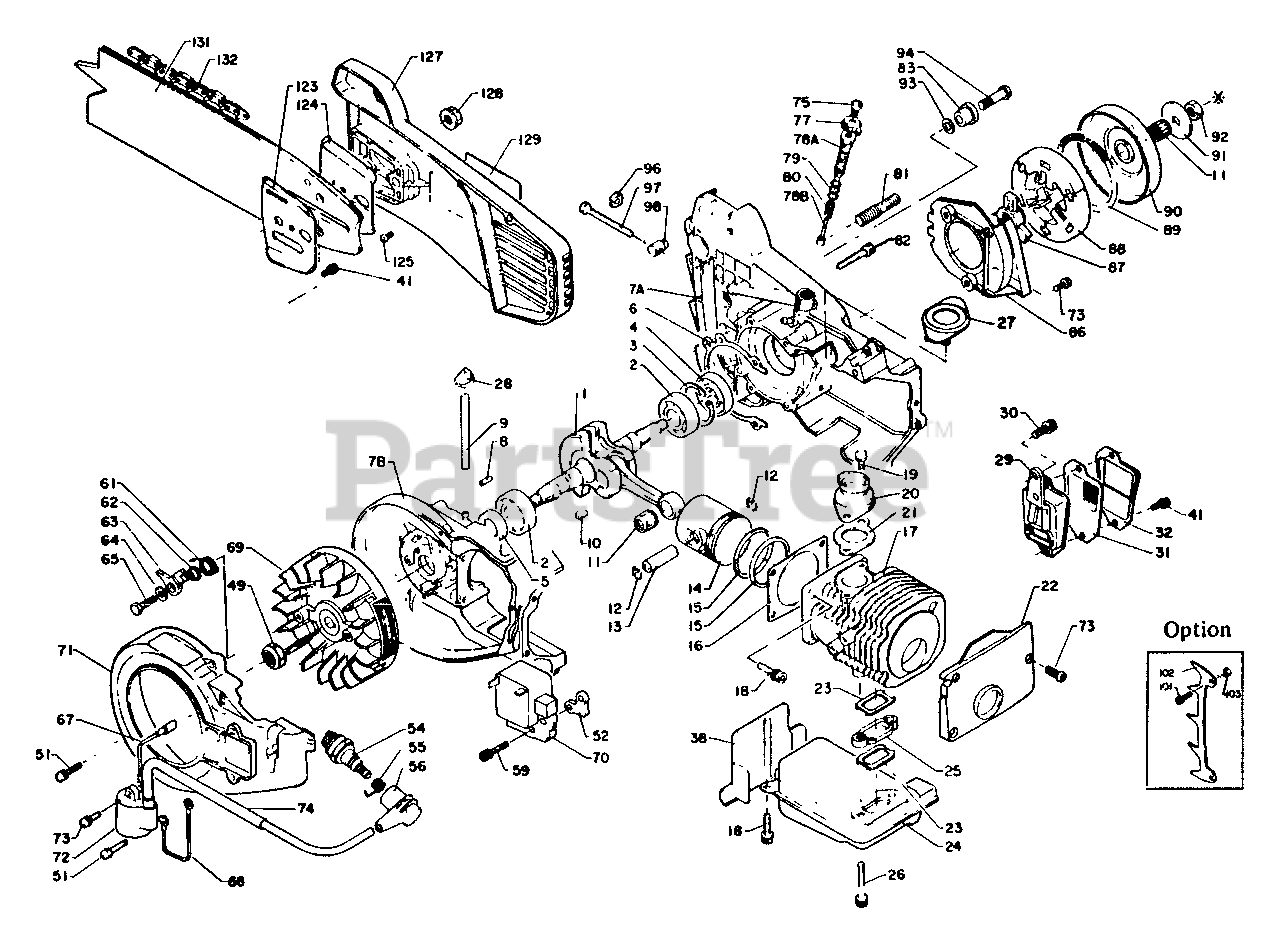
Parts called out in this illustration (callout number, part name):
1	CRANKSHAFT ASSY
2	BEARING, BALL 6202
3	RING, SNAP 35
4	SEAL, OIL 18
5	SEAL, OIL
6	GASKET, CRANKCASE
7	CRANKCASE KIT
7A	CRANKCASE KIT
7B	CRANKCASE KIT
8	PIN, LOCATING 4
9	PIPE, IMPULSE 3×6×75
10	KEY, WOODRUFF
11	BEARING, NEEDLE
12	RING, SNAP 8
13	PIN, PISTON
14	PISTON
15	RING, PISTON
16	GASKET, CYLINDER
17	CYLINDER
18	BOLT 5×20
19	SCREW 5×10
20	ADAPTOR, INTAKE
21	GASKET, INTAKE
22	COVER, CYLINDER
23	GASKET, EXHAUST
24	MUFFLER
25	BAFFLE, MUFFLER
26	BOLT 5×45
30	BOLT 5×14
31	SCREEN, SPARK ARRESTER
32	GUIDE, EXHAUST
38	INSULATOR
41	SCREW 4×10
51	SCREW 4×20
54	SPARK PLUG - BPM6A
55	TERMINAL, SPARK PLUG
56	CAP, SPARK PLUG
59	SCREW 4×22
62	SPACER
63	RATCHET
64	WASHER 5.5×12×0.8
65	BOLT - 5×20
67	LEAD
68	LEAD - GROUND
69	FLYWHEEL
70	COIL, IGNITION
71	SHIELD, FAN
72	COIL, IGNITION
73	SCREW 4×14
74	PIPE
75	SCREW 5×10
77	WASHER, LOCK
78	AUTO-OILER ASSY
78A	AUTO-OILER ASSY
78B	AUTO-OILER ASSY
81	STUD, GUIDE BAR
82	BOLT 5×30
83	CHAIN CATCHER KIT
87	HUB, CLUTCH
88	SHOE, CLUTCH
89	SPRING, CLUTCH
90	DRUM, CLUTCH - 3/8"
91	WASHER, CLUTCH
92	LOCKNUT
93	WASHER, FLAT 5.5×10×0.8
94	SCREW 5×25
97	SCREW, ADJUSTER
98	TENSIONER, CHAIN
101	BOLT 5×12
102	BUMPER, SPIKED
103	NUT M5
123	PLATE, SIDE
124	PLATE, SIDE
125	SCREW 3×6
127	GUARD, SPROCKET
128	NUT, FLANGE M8×1.25
129	LABEL - ECHO
131	GUIDE BAR
